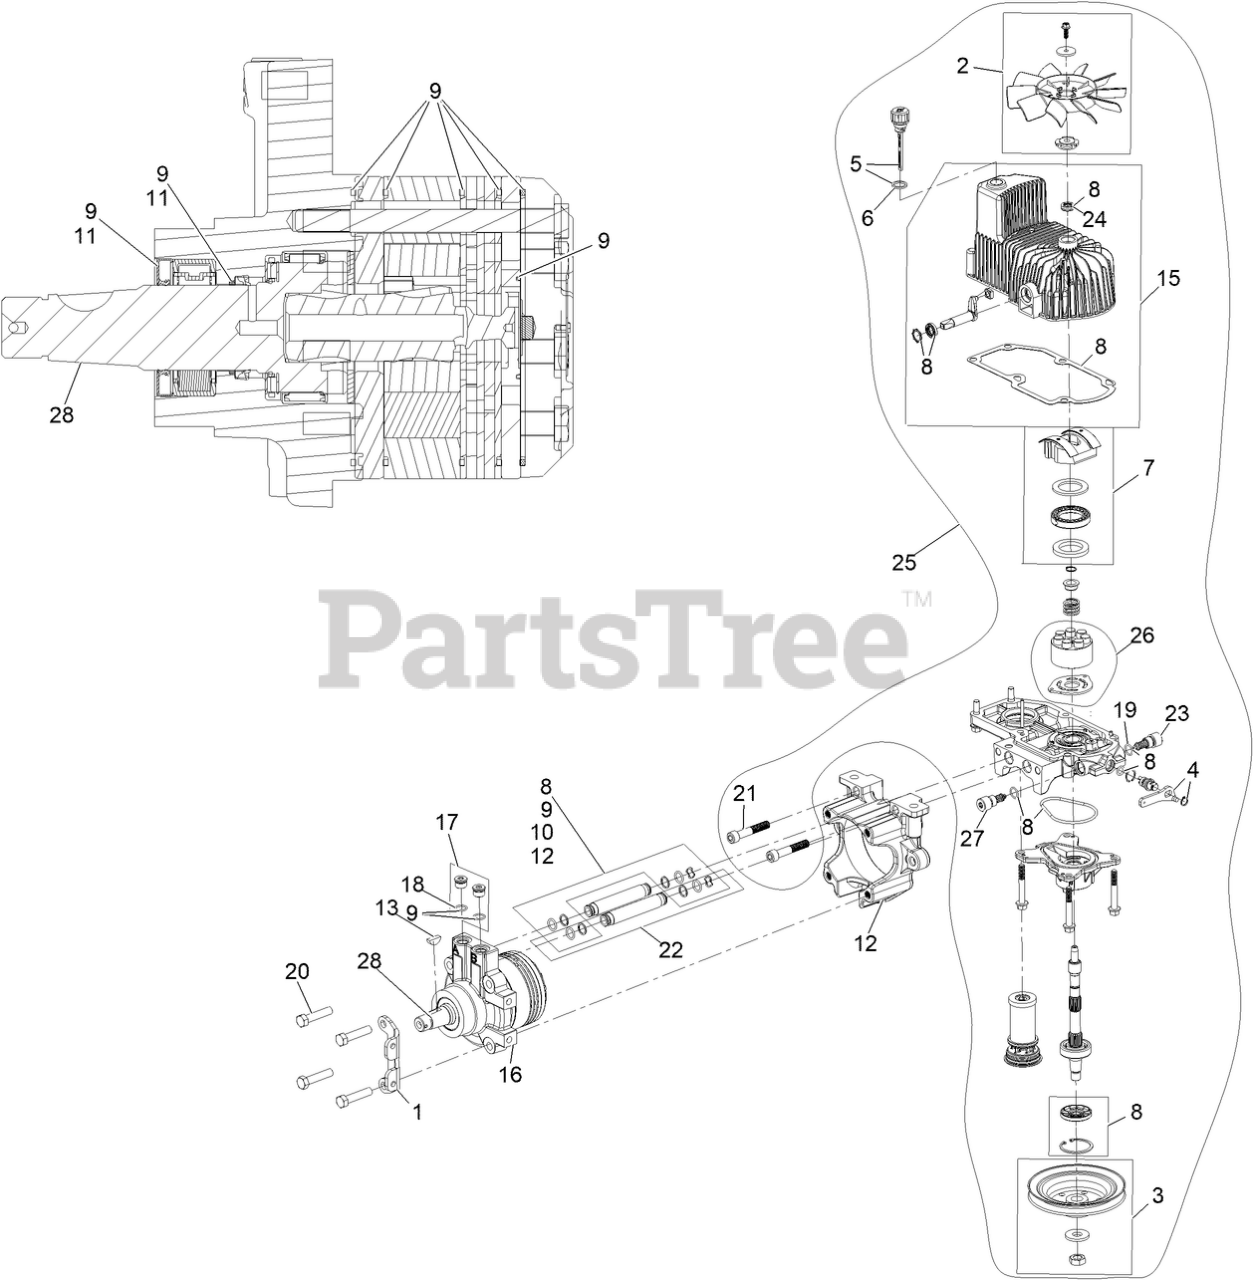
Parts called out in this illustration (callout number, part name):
1	PLATE, HORSE SHOE MOUNT
2	KIT, 7.8 IN FAN
3	PULLEY KIT
4	HANDLE-BYPASS VALVE, HYDRO
5	DIPSTICK-HYDRO W/GASKET
6	GASKET-DIPSTICK, HYDRO
7	SWASH BLOCK KIT
8	KIT, PUMP SEAL
9	MOTOR SEAL KIT
10	TUBE SEAL KIT
11	OUTPUT SHAFT SEAL KIT
12	NOSE CUP-UHT
13	KEY-WOODRUFF
15	KIT, HOUSING-HYDRO LH
16	KIT, MOTOR TG310CC LH
17	MAGNETIC PLUGS SERVICE KIT
18	O-RING
19	O-RING-CHECK VALVE
20	SCREW HH
21	SCREW-HSH
22	HYDRAULIC TUBE KIT
23	SHOCK VALVE, 12CC HYDRO
24	SEAL-FAN DRIVE
25	KIT, PUMP SECTION 16CC LH
26	KIT - 16CC PORT PLATE,ROTATE GRP
27	SHOCK VALVE ORIFICED 3800
28	SHAFT-COUPLING
